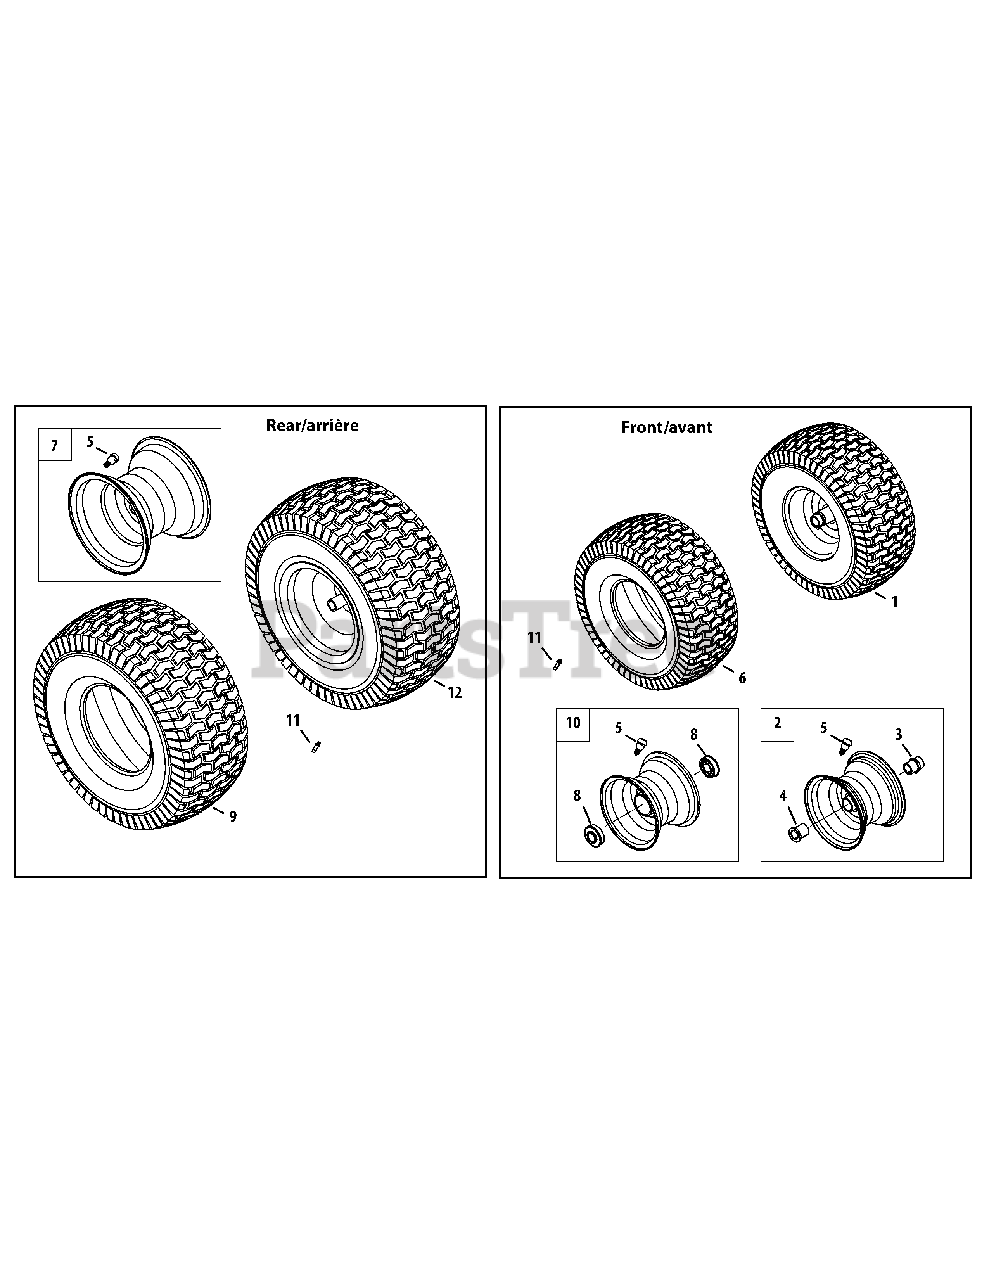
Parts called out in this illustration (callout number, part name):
1	Wheel Ass’y, 15 x 6 Plst. Brg. (Grey)
2	Rim Ass’y, Plst. Brg. (Grey)
3	Flg. Bearing .760 ID w/fitting
4	Flg. Bearing .760 x 1.0 x 1.20
5	Air Valve
7	Rim Ass’y, 8.0 x 7.0 x .750 (Grey)
8	Ball Bearing .750 ID x 1.750 OD
9	Tire, 20 x 8 x 8 Square Shoulder
10	Rim Ass’y, Ball Brg. (Beige)
11	Grease Fitting
12	Wheel Ass’y, 20 x 8 (Grey)
